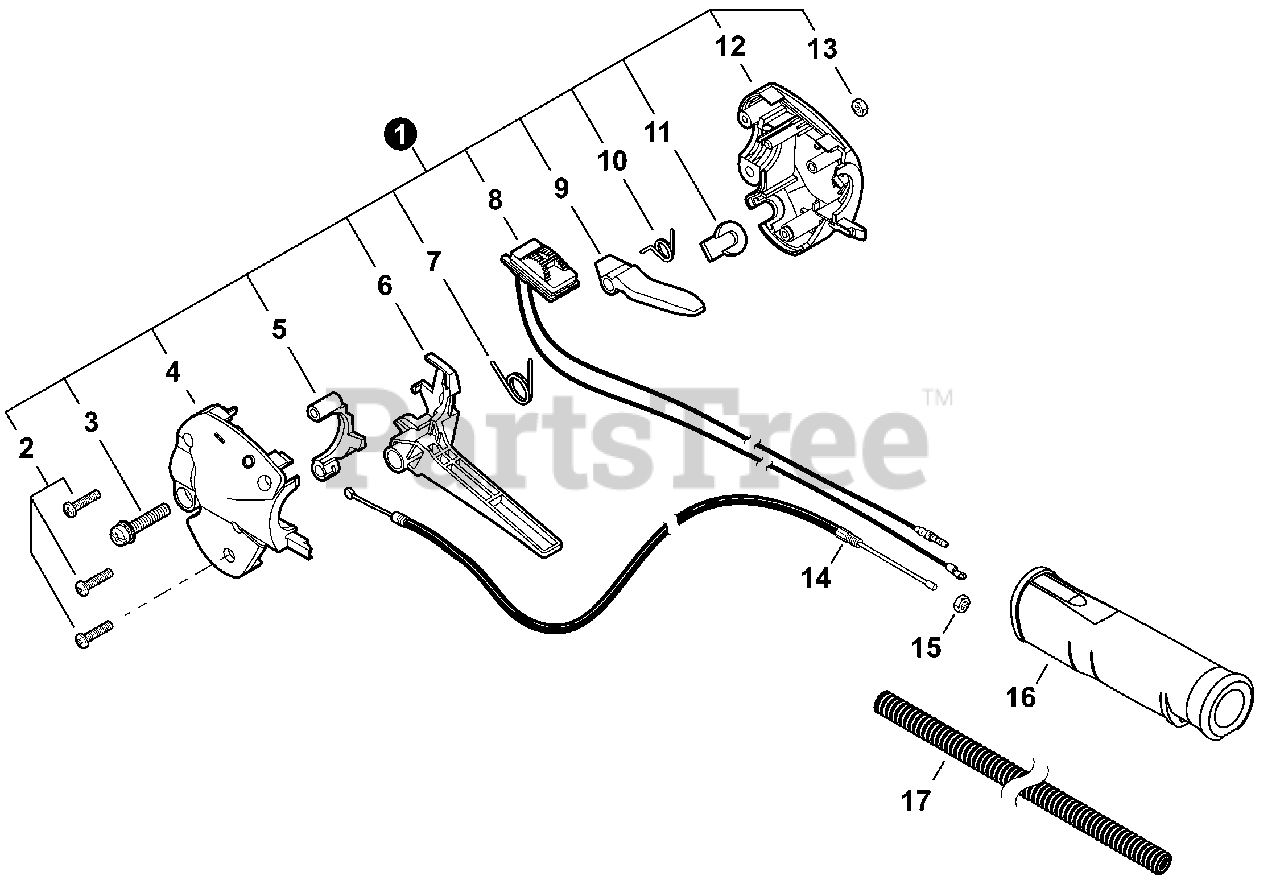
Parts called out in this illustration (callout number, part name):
1	THROTTLE CONTROL ASSY
2	SCREW, TAPPING M4×20
3	SCREW M5×20
4	CONTROL HANDLE - LEFT
5	LOCKOUT, THROTTLE
6	TRIGGER, THROTTLE
7	SPRING, THROTTLE RETURN
8	SWITCH, ON-OFF
9	LEVER, THROTTLE LOCKOUT
10	SPRING, THROTTLE LOCKOUT
12	CONTROL HANDLE - RIGHT
14	CABLE, THROTTLE
16	GRIP, REAR
17	TUBE, PLASTIC PROTECTIVE
